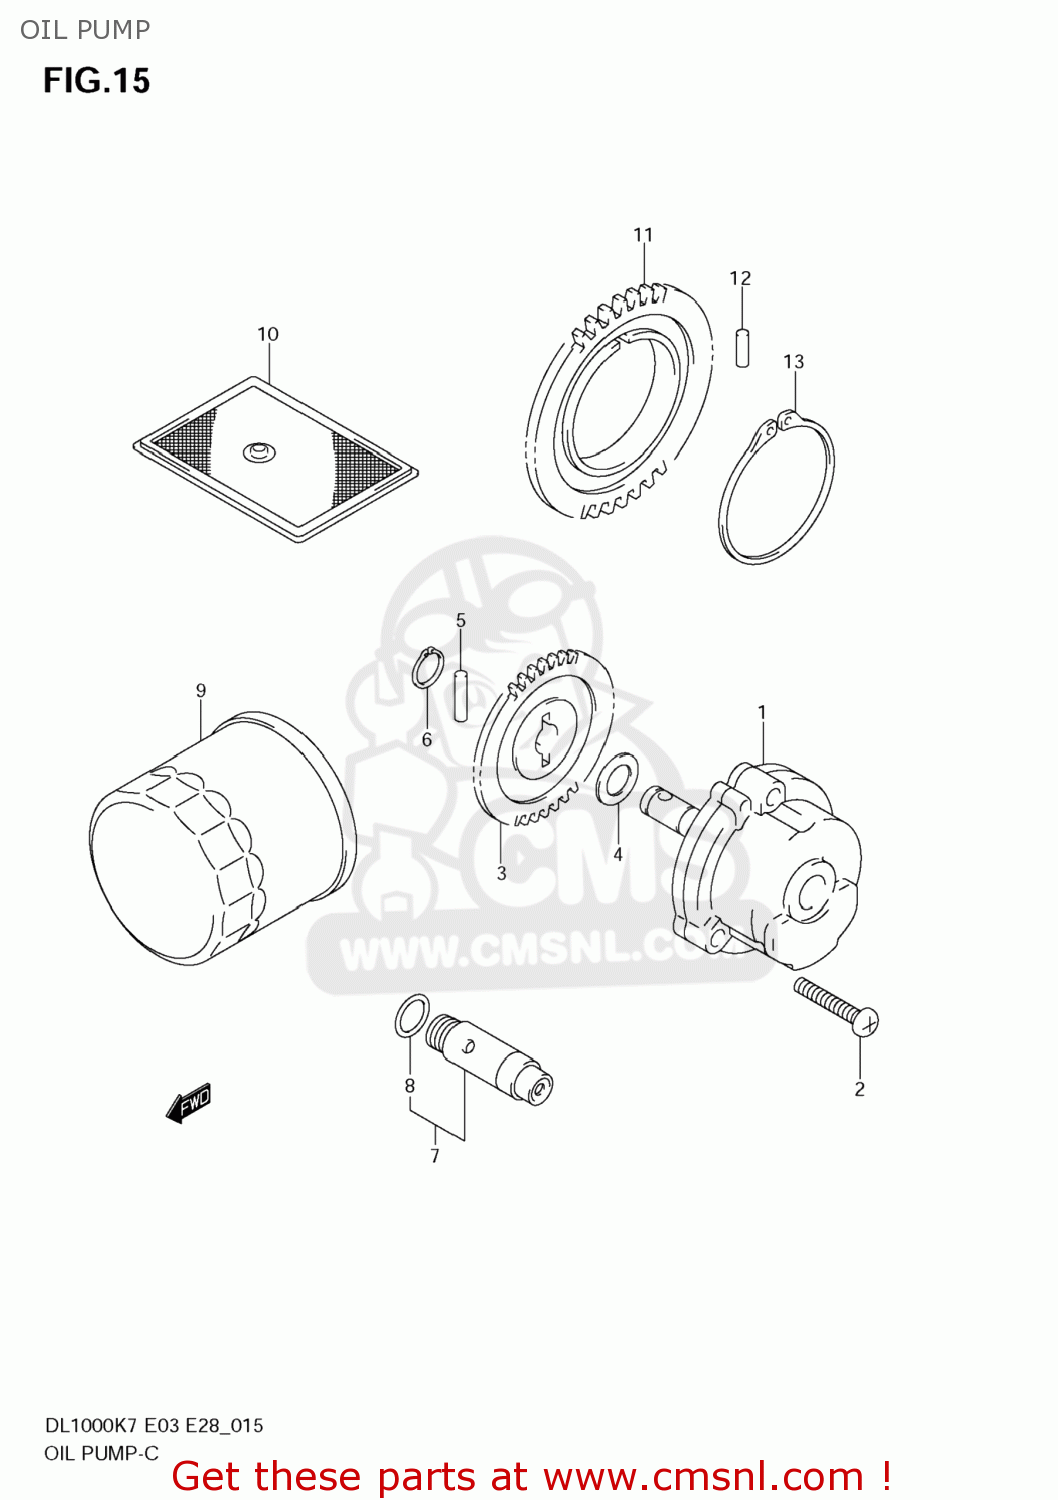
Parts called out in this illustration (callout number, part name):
1	PUMP ASSY,ENGINE OIL
2	BOLT
3	GEAR,OIL PUMP DRIVEN
4	SHIM(10X18X0.5)
5	PIN(4X15.8)
6	CIRCLIP,10MM
7	VALVE ASSY,OIL RELIEF(7K)
8	O RING(D:1.9,ID:13)
9	FILTER ASSY,EN
10	STRAINER,ENGINE OIL
11	GEAR,ENG OIL PUMP DRIVE
12	PIN(6X6)
13	CIRCLIP
